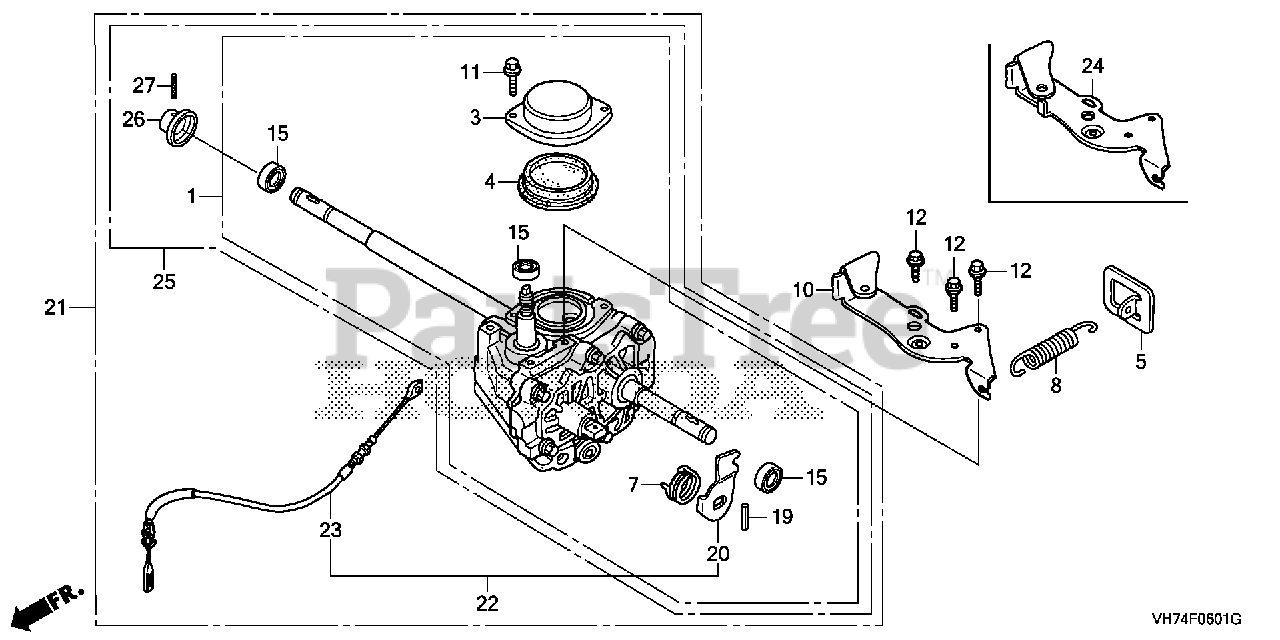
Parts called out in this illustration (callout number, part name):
3	CAP, OIL
4	GASKET, OIL CAP
5	PLATE, TENSION SPRING
7	SPRING, CONTROL ARM RETURN
8	SPRING, WHEEL TENSION
11	BOLT, FLANGE (5X12)
12	BOLT, FLANGE (6X16)
15	OIL SEAL (13X22X5) (ARAI)
19	PIN, SPRING (4X22)
20	ARM, CONTROL
23	CABLE, CHANGE
24	HOLDER, WIRE
25	TRANSMISSION ASSY.
26	GUARD, GRASS
27	PIN, SPRING (3X20)
